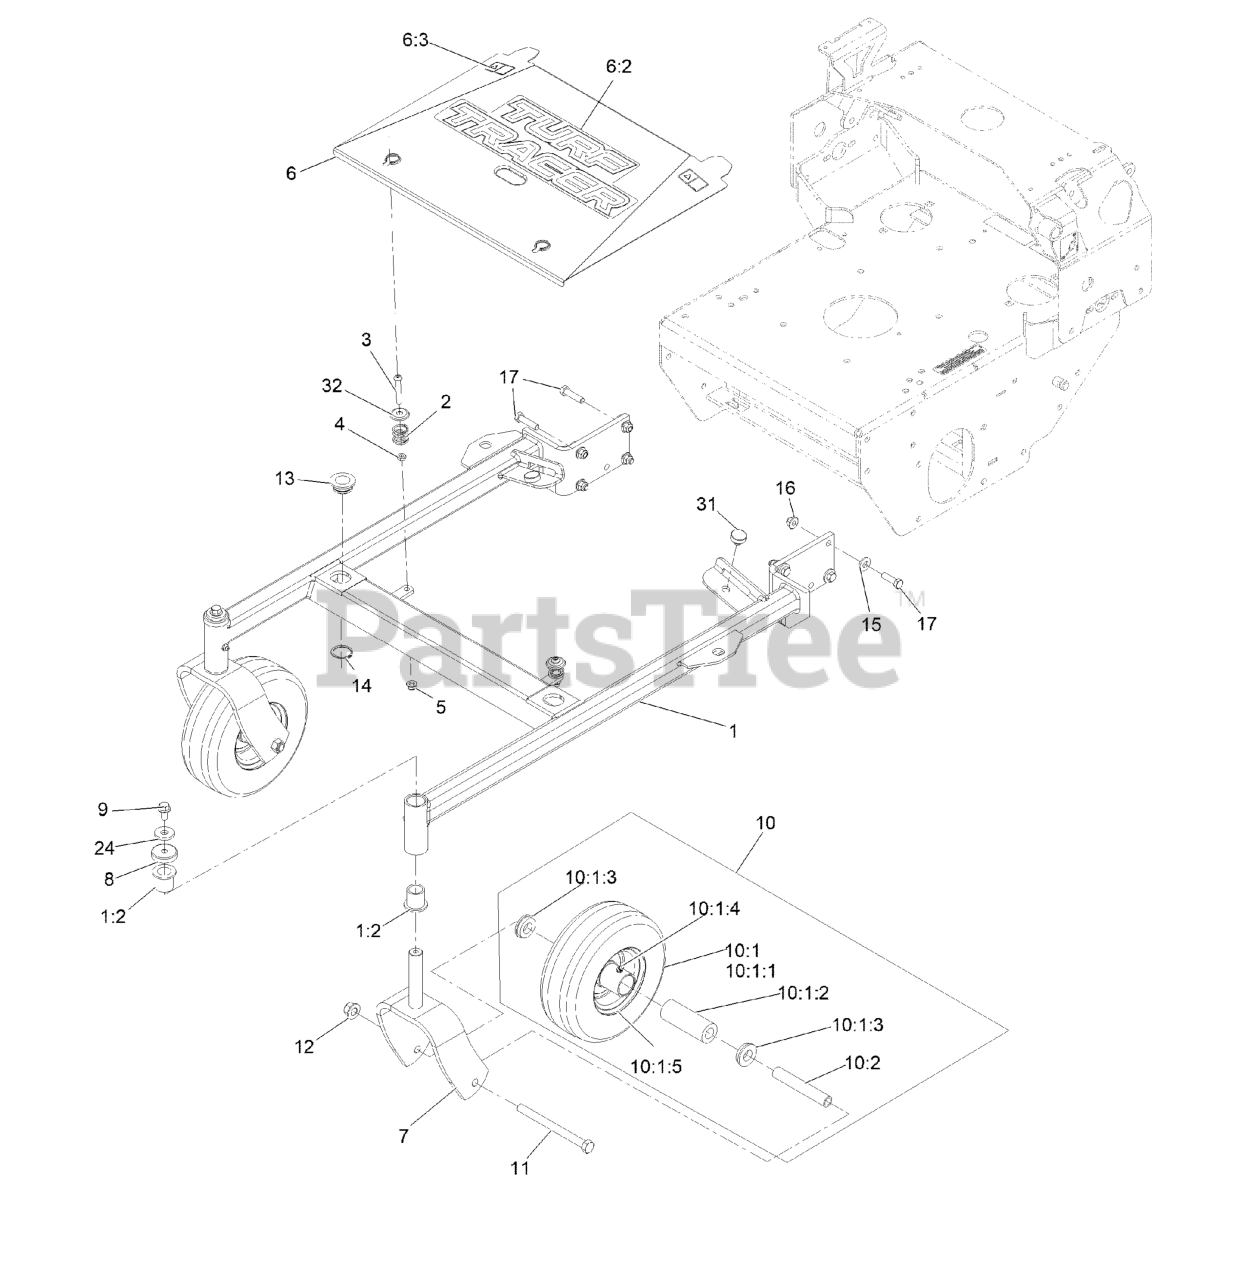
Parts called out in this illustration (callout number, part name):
1	ASM-36" Tts Front Frame
1:2	BEARING-FLANGED
3	SCREW-HSBH
4	NUT-JAM
5	NUT-HF, NI
6	ASM-36" Tts Center Shield
6:2	DECAL-TURF TRACER
6:3	DECAL-WARNING
7	FORK, CASTER
8	CAP, DUST
9	SCREW-HHF
10	KIT, SP CASTER WHEEL REPLACEMENT
10:1	Wheel And Tire ASM
10:1:1	Tire
10:1:2	BEARING
10:1:3	BUSHING
10:1:4	FITTING-GREASE
10:1:5	Wheel
11	SCREW-HH
12	Nut-Lock 1/2-13
13	BUSHING-DECK
14	RING-RETAINING
15	WASHER-BELLEVILLE
16	NUT-HF, NI
17	SCREW-HH
31	BUMPER-RUBBER
32	Washer-Cup
